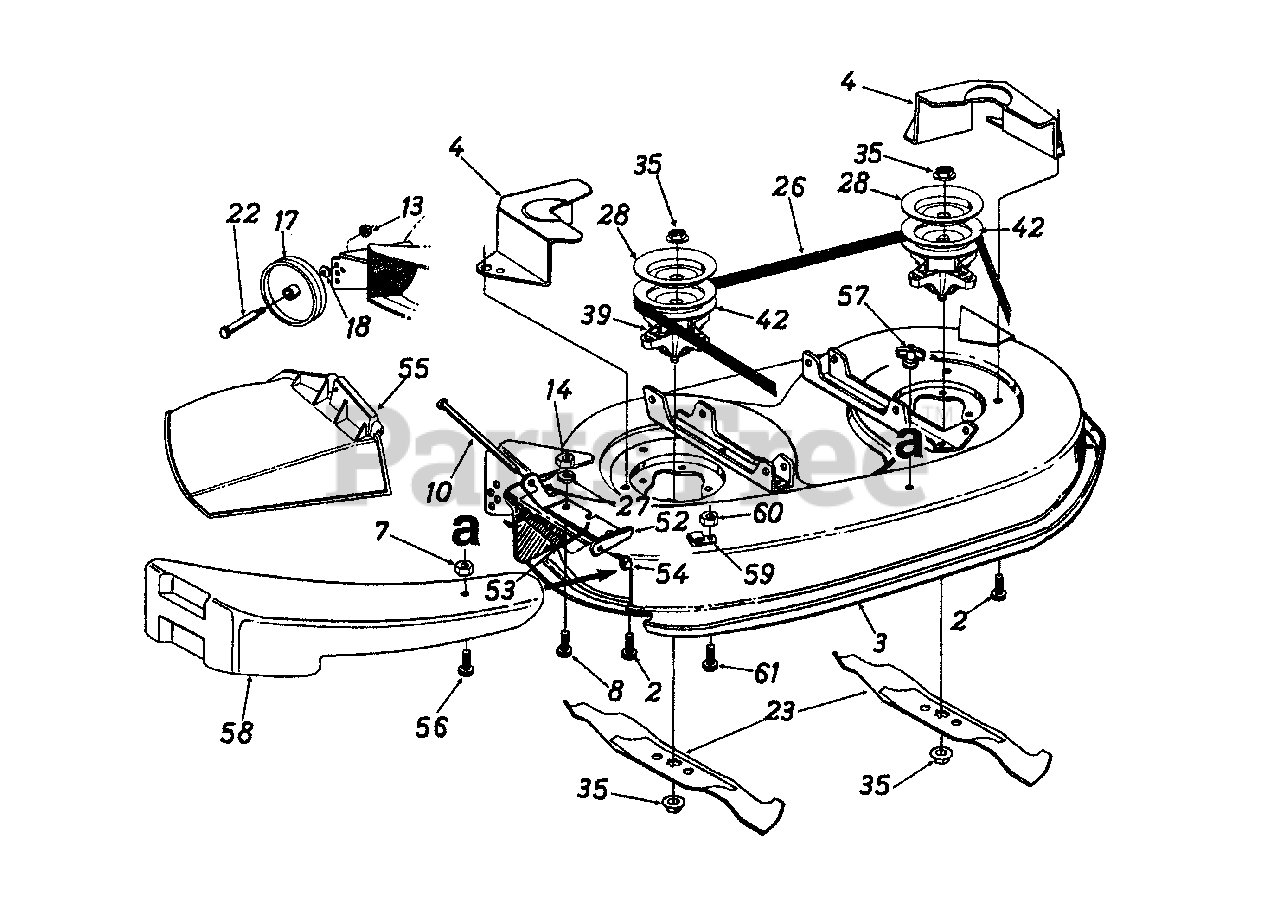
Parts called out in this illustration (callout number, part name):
2	Hex Wash. Hd. TT-Tap Scr. 5/16-18 x .75" Lg.
7	Hex L-Nut 1/4-20 Thd.
8	Hex Bolt 1/4-20 x .62"
10	Hinge Pin
13	Hex Top L-Nut 3/8-16 Thd.
14	Hex Nut 1/4-20 Thd. (Gr. 5)
17	Deck Wheel--5"
18	Bell-Wash. .40" I.D. x .88" O.D.
22	Shld. Bolt .498" Dia. x 1.53"
23	3 in 1 Blade
26	V-Belt
27	Bell-Wash. 1/4" I.D.
28	Brake Disc
35	Hex Flange Nut 5/8-18 Thd.
39	Blade Spindle Ass'y. Comp.
42	5.75" Dia. Pulley
52	Hinge Mtg. Brkt.
53	Torsion Spring
54	Push Nut
55	Chute Ass'y. Comp.
56	Hex Bolt 1/4-20 x 1" Lg.
57	Wing Nut 1/4-20 Thd.
58	Mulching Plug
59	Retainer Hook Brkt.
60	Hex Sems Nut 1/4-20 Thd.
61	Hex Bolt 1/4-20 x .62" Lg.
